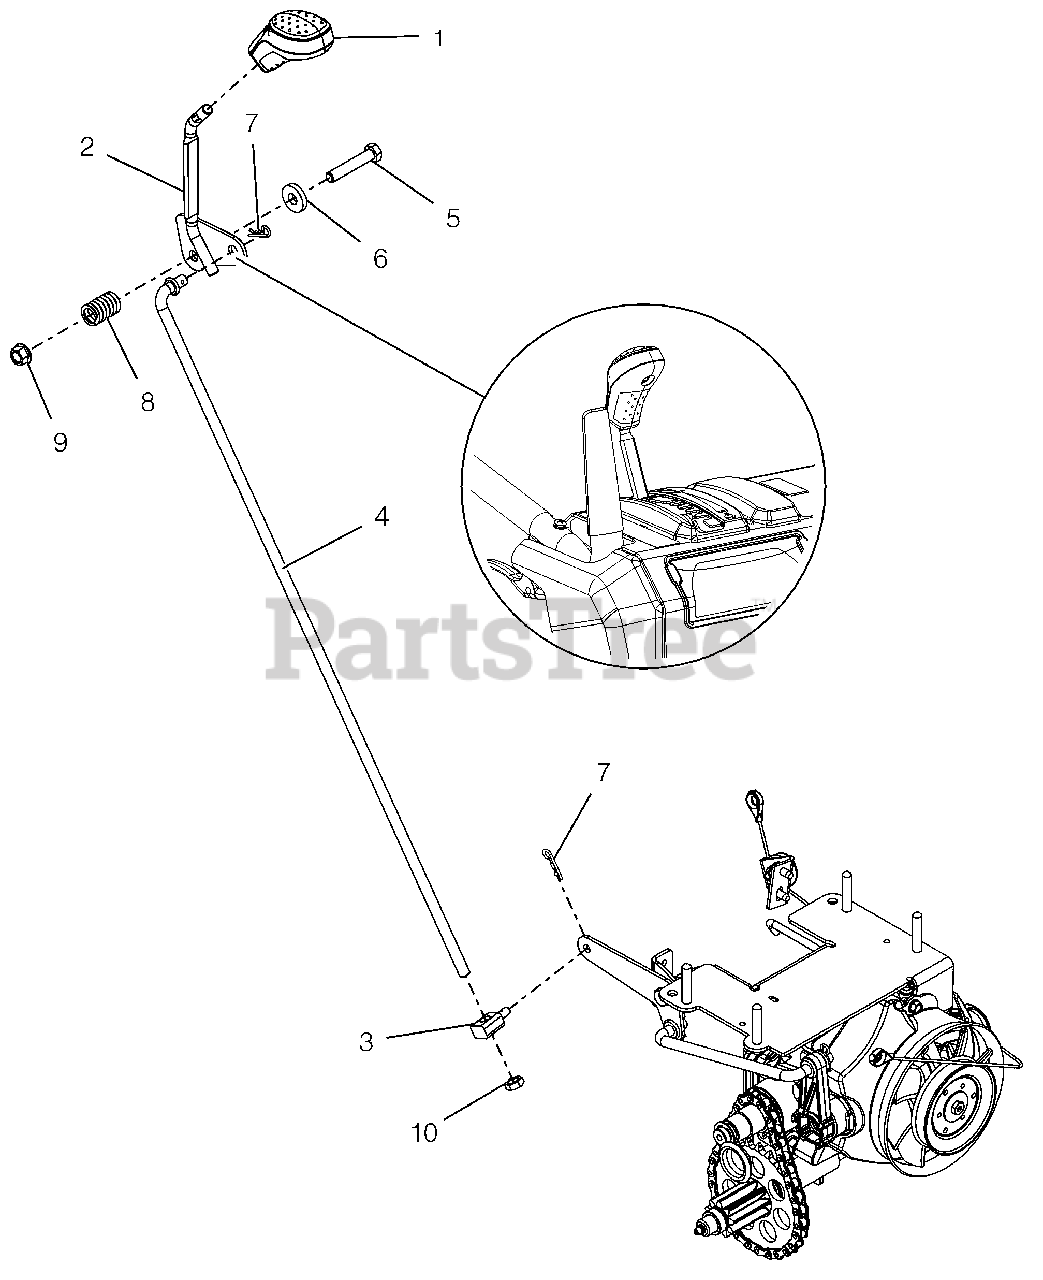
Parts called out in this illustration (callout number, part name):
1	KNOB, CONTROL, DASH
2	WELDMENT,LG DASH SPEED CONTROL
3	PIVOT,SHIFT ROD .375-16(TRUNN)
4	ROD, SHIFT-PRO
5	@BLT-HEX .38-16X2.00 GR5 YWZC
6	WSHR-FL-STL .406X1.00X.188 YWZ
7	PIN-HAIR INT .08X.18X1.18 YWZC
8	SG-COMP .125X.781X1.250
9	@NUT-LK-TOP-FLG .38-16 YWZC
10	NUT-HEX-JAM .375-16 YWZC
